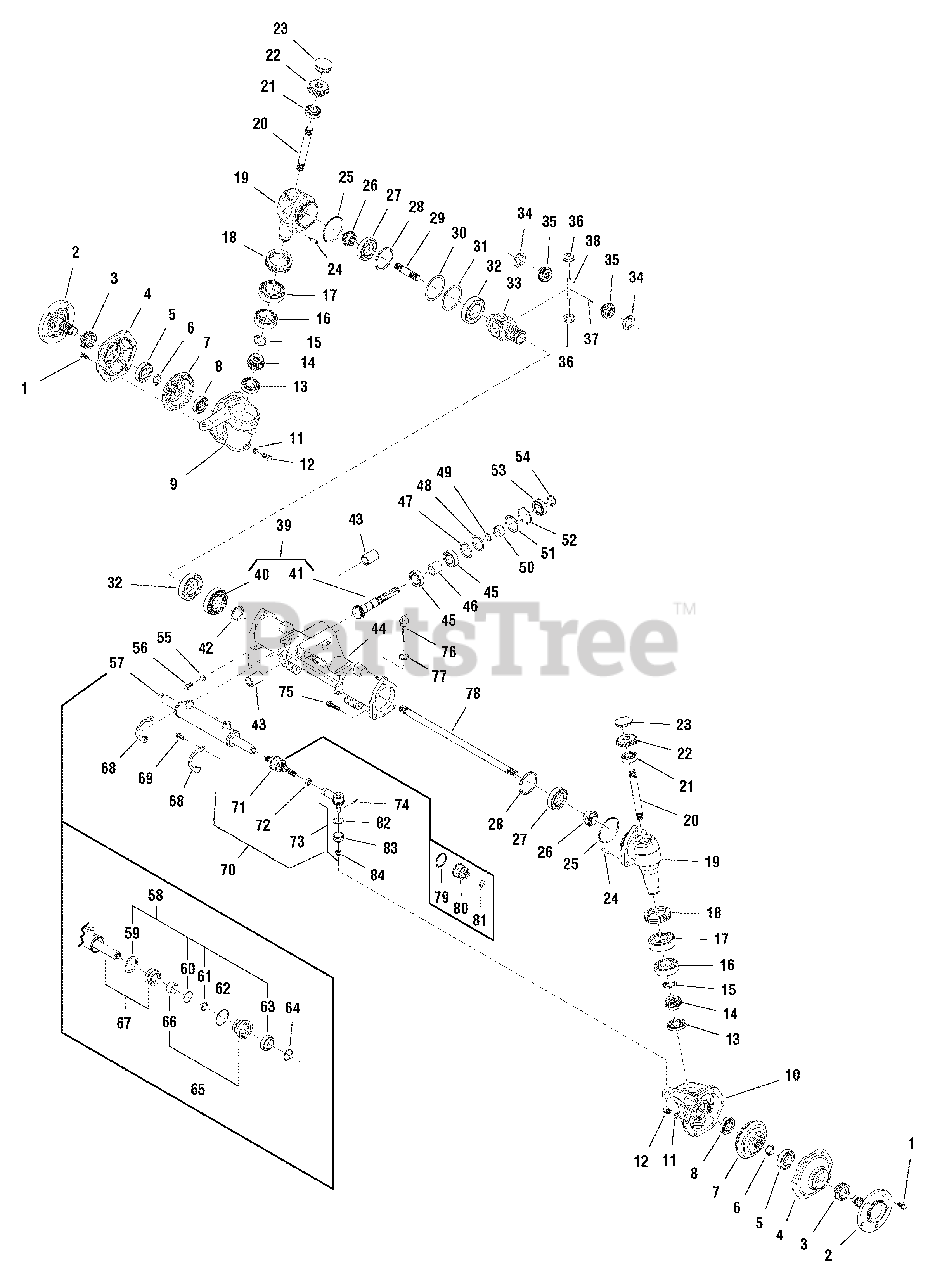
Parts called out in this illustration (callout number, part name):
2	WHEEL SHAFT
5	BALL BEARING
8	BALL BEARING
9	MISSION CASE, R
10	MISSION CASE, L
11	SEAL WASHER
13	BALL BEARING
14	FINAL PINION
16	BALL BEARING
17	BALL BEARING
19	MISSION CASE, Upper
20	DRIVE SHAFT
21	BALL BEARING
22	FINAL PINION
26	FINAL PINION
27	BALL BEARING
29	DIFF SHAFT, R
32	BALL BEARING
33	DIFF HOUSING
34	THRUST WASHER
36	DIFF PINION
38	PINION SHAFT
39	DRIVE PINION ASSY
40	RING GEAR
41	DRIVE PINION
44	WHEEL SHAFT CASE
45	BALL BEARING
55	SEAL WASHER
57	CYLINDER ASSY, M16 x 1 Female Thread
57	CYLINDER ASSY, M16 x 1.5 Female Thread
58	REPAIR, KIT
59	PISTON PACKING
60	O-RING
61	ROD PACKING
62	O-RING
63	DUST SEAL
65	GUIDE KIT
67	PISTON ROD KIT
71	TIE ROD END, M16 x 1 Male Thread
71	TIE ROD END, M16 x 1.5 Male Thread
73	BALL JOINT, TIE ROD END
77	SEAL WASHER
78	DIFF SHAFT, L
79	RING RETAINING, LARGE, TIE ROD
80	BOOT RUBBER, TIE ROD
81	RING RETAINING, SMALL TIE ROD
82	RING RETAINING, BALL JOINT
83	BOOT RUBBER, BALL JOINT
84	NUT, CASTLE, BALL JOINT
